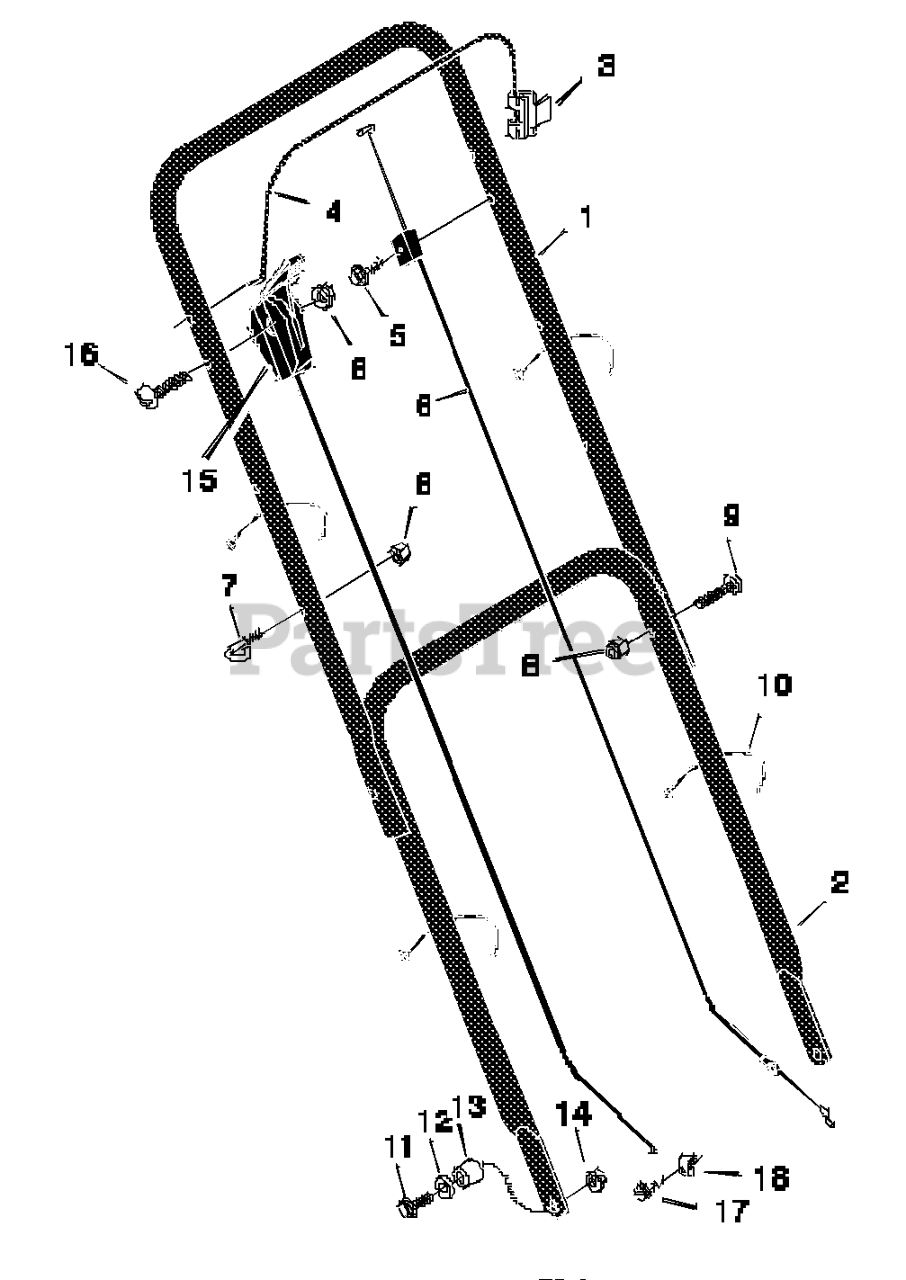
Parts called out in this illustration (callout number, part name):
1	Handle, Upper (Black)
2	Handle, Lower (Black)
3	Bracket, Stop Lever
4	Lever, Stop
6	Engine Stop Cable
7	GUIDE, ROPE
8	Locknut
10	Fastener, Cable
11	Bolt
14	Nut
15	Control, Throttle
